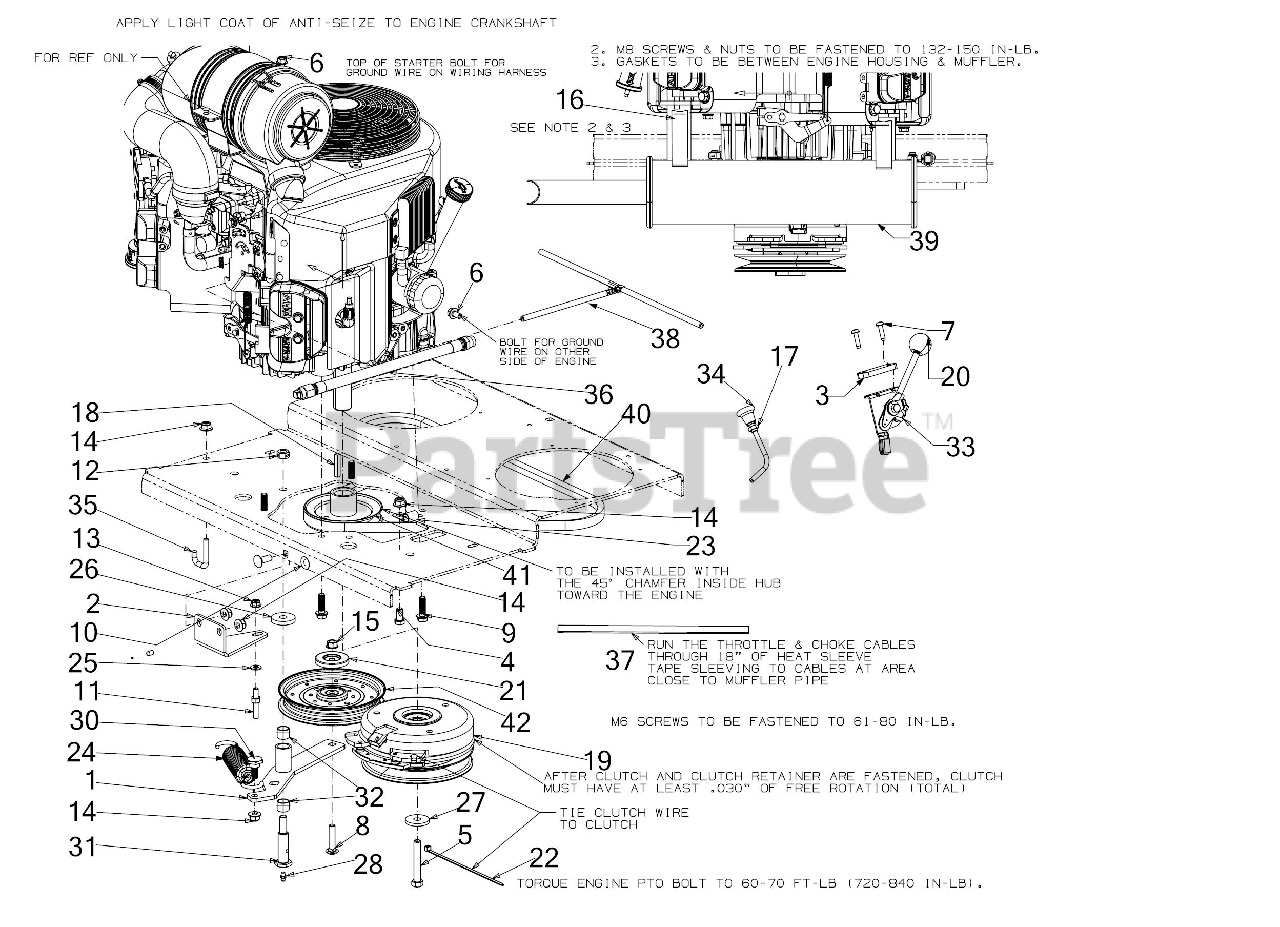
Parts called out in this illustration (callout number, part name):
1	TRANSMISSION IDLER BRACKET
2	RETAINER BRACKET
3	THROTTLE CABLE SPACER
4	HEX SCREW 3/8-16 x .75
5	SCREW 7/16-20:2.75 GR5
6	SCREW M8 x 1.25 x 16MM GR8.8
7	SCREW 1/4-20 x 1.0
8	CARRIAGE BOLT 3/8-16 x 1.75 GR5
9	SCREW 3/8-16 x 1.25 GR5
10	CARRIAGE BOLT 3/8-16 x 1.00 GR5
13	FLANGE LOCK NUT 5/16-18
15	HEX LOCK NUT
16	HEX FLANGE NUT
17	HEX JAM NUT 3/8X24
18	SQUARE KEY 1/4 x 1.50
19	ELECTRIC PTO CLUTCH
21	PULLEY CAP
22	7" CABLE TIE
23	J TYPE CLIP
24	EXTENSION SPRING W/HOOK
25	FLAT WASHER
26	FLAT WASHER 47 x 1.50 x .225
27	FLAT WASHER .45 x 1.5 x .172 HT
28	GREASE FITTING
30	SHOULDER SCREW .625 x .302 x 3/8-16
31	SHOULDER BOLT 7/16-14
32	SLEEVE BEARING
33	THROTTLE CABLE 59"
34	CHOKE CABLE
35	ROD SPRING HOOK
36	OIL DRAIN HOSE
37	HEAT SHIELD
38	ROLLOVER VENT HOSE ASSEMBLY
39	MUFFLER - KAWASAKI 1000
40	TRANSMISSION BELT 61.5
41	PULLEY - PUMP DRIVE
42	IDLER PULLEY
